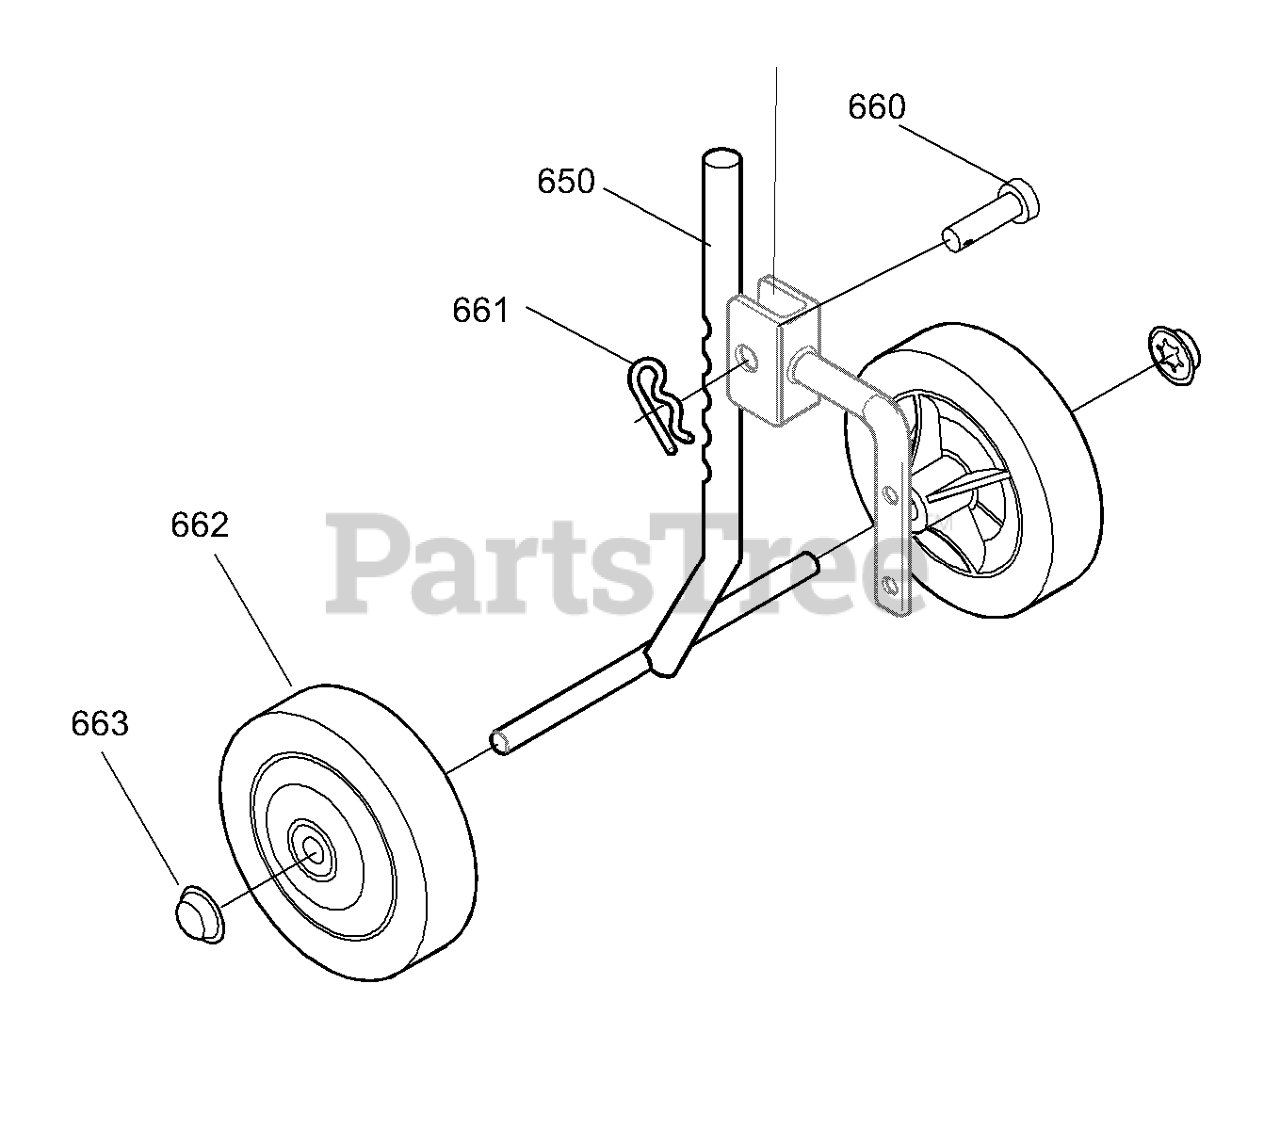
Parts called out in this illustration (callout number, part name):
650	Wheel Support Assy.
660	Clevis Pin
661	Hair Pin
662	Tire & Rim
663	Push On Nut
